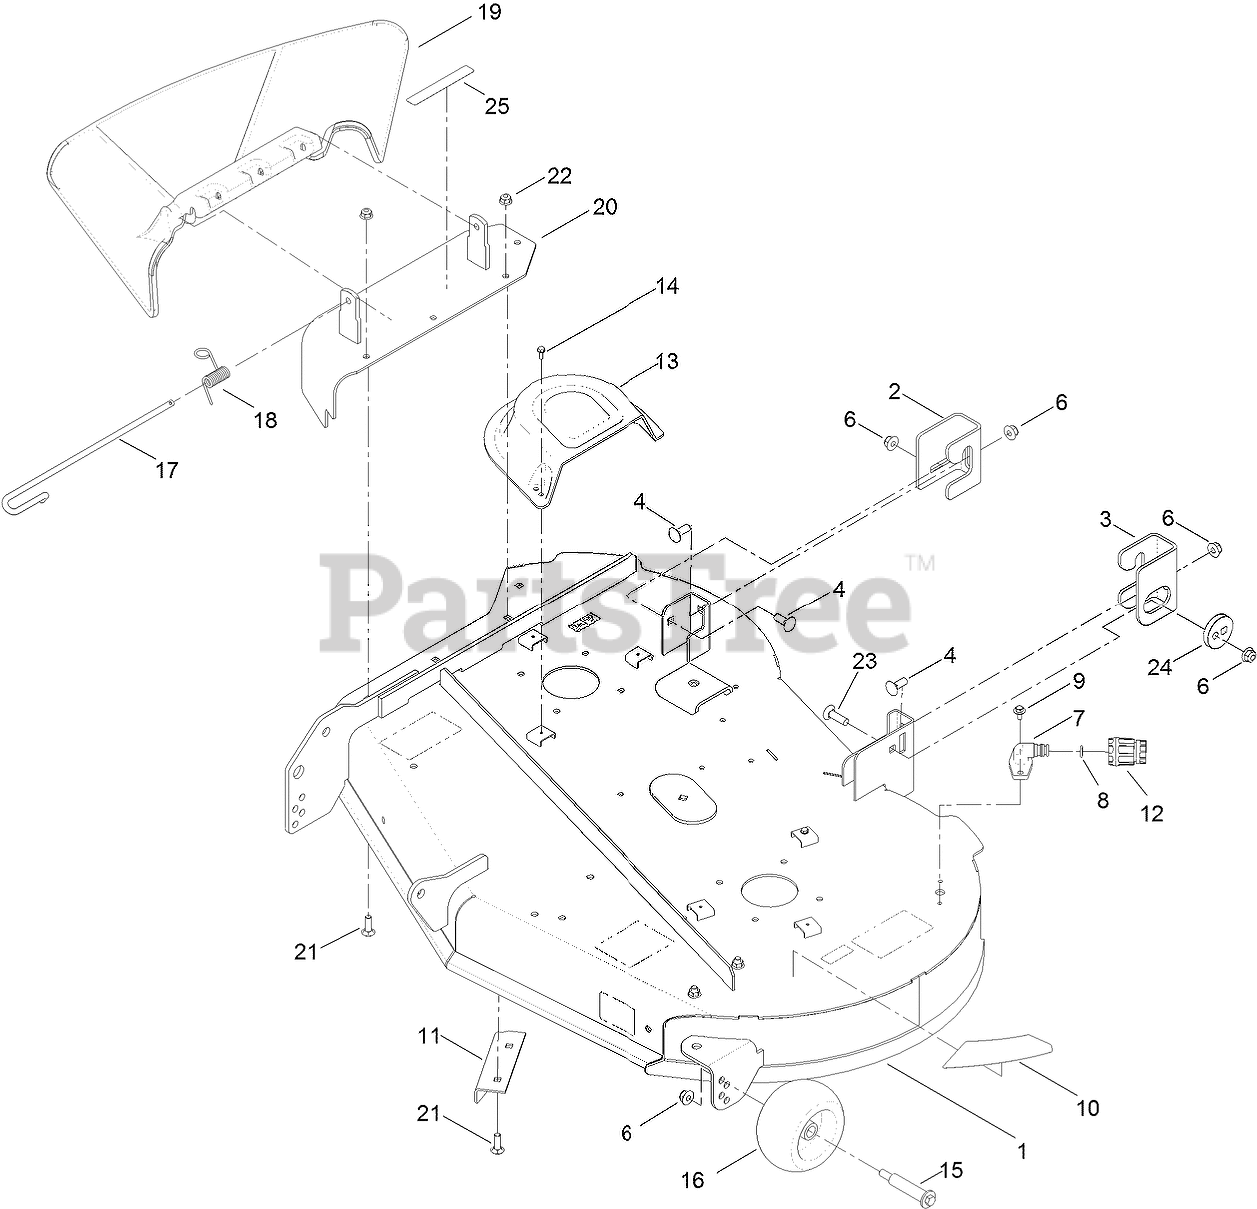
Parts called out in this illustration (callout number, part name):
1	42 INCH DECK AND DECAL ASM
2	BRACKET-HANGER, RH
3	BRACKET-HANGER, LH
4	BOLT-CARR
6	NUT-HF, NI
7	FITTING-WASHOUT
8	O-RING
9	SCREW-HHFTF
10	DECAL-DECK
11	BAFFLE-CUTOFF
12	CONNECTOR-HOSE
13	COVER-BELT
14	SCREW-TAPTITE
15	BOLT-SHOULDER
16	ROLLER-SCALP, ANTI
17	PIN-CHUTE
18	SPRING-TORSION
19	DEFLECTOR-DISCHARGE
20	DISCHARGE COVER ASM
21	SCREW-CARR
22	NUT-HF, NI
23	SCREW-CARR
24	ECCENTRIC
25	DECAL-DANGER
